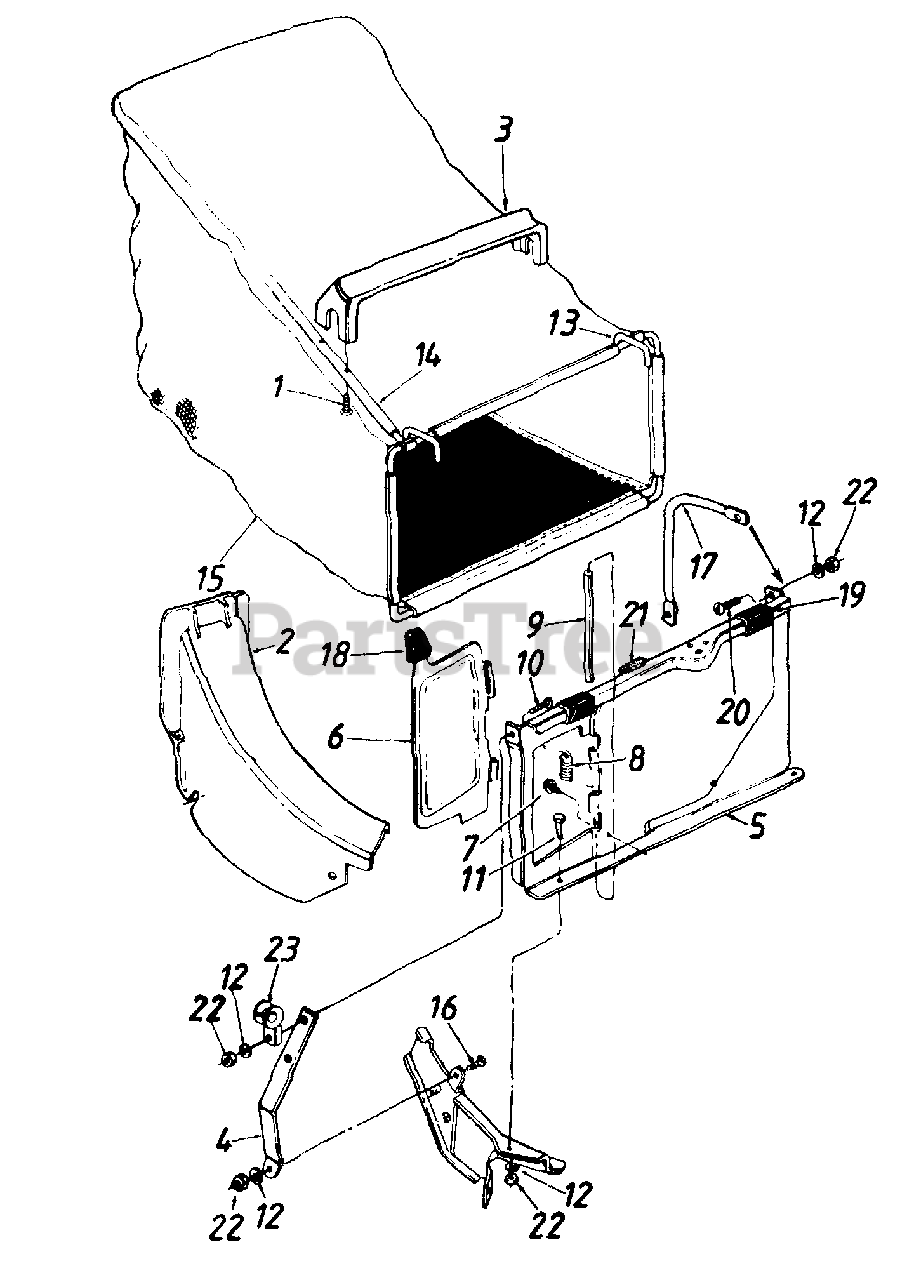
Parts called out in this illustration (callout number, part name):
1	Hex AB-Tap Scr. #12 x 1.25" Lg.
2	Rear Discharge Chute Ass'y.
7	Hex B-Tap Scr. #10 x .38"
8	Torsion Spring
10	Truss Mach. Scr. 1/4-20 x 3/4" Lg.
11	Hex Bolt 1/4 20 x .50" Lg.
12	L-Wash. 1/4" I.D.
15	21" Rear Discharge Grass Bag
16	Hex Bolt 1/4-20 x .62" Lg.
17	Catcher Panel Support Arm
18	Door Grip
19	Panel Clip
20	Truss Mach. Scr. 1/4-20 x .62" Lg.
22	Hex Nut 1/4-20 Thd.
